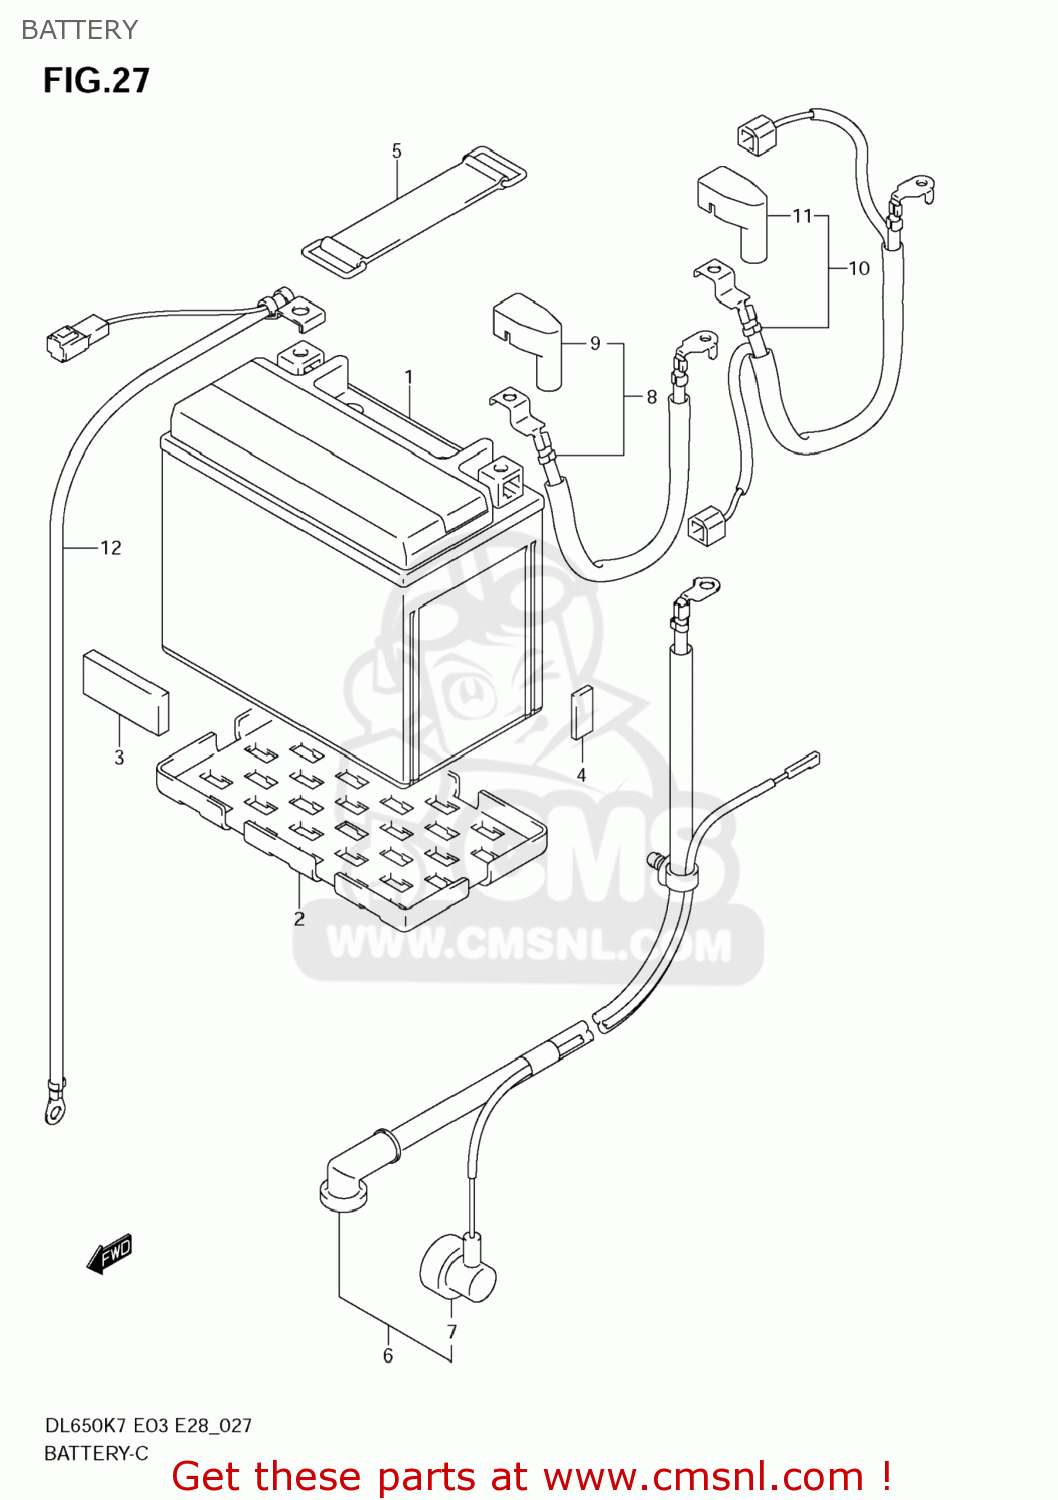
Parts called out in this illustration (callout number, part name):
1	BATTERY ASSY(YTX12-BS,12V10AH)
2	PROTECTOR,BATTERY
3	PROTECTOR,BATTERY(70X100X6)
4	CUSHION
5	BAND
6	WIRE,STARTER MOTOR LEAD
7	CAP,OIL PRESSURE SWITCH
8	WIRE,BATTERY PLUS LEAD
9	CAP,BATTERY PLUS LEAD
10	WIRE,BATTERY PLUS LEAD
11	CAP,BATTERY PLUS LEAD
12	WIRE,BATTERY MINUS LEAD
